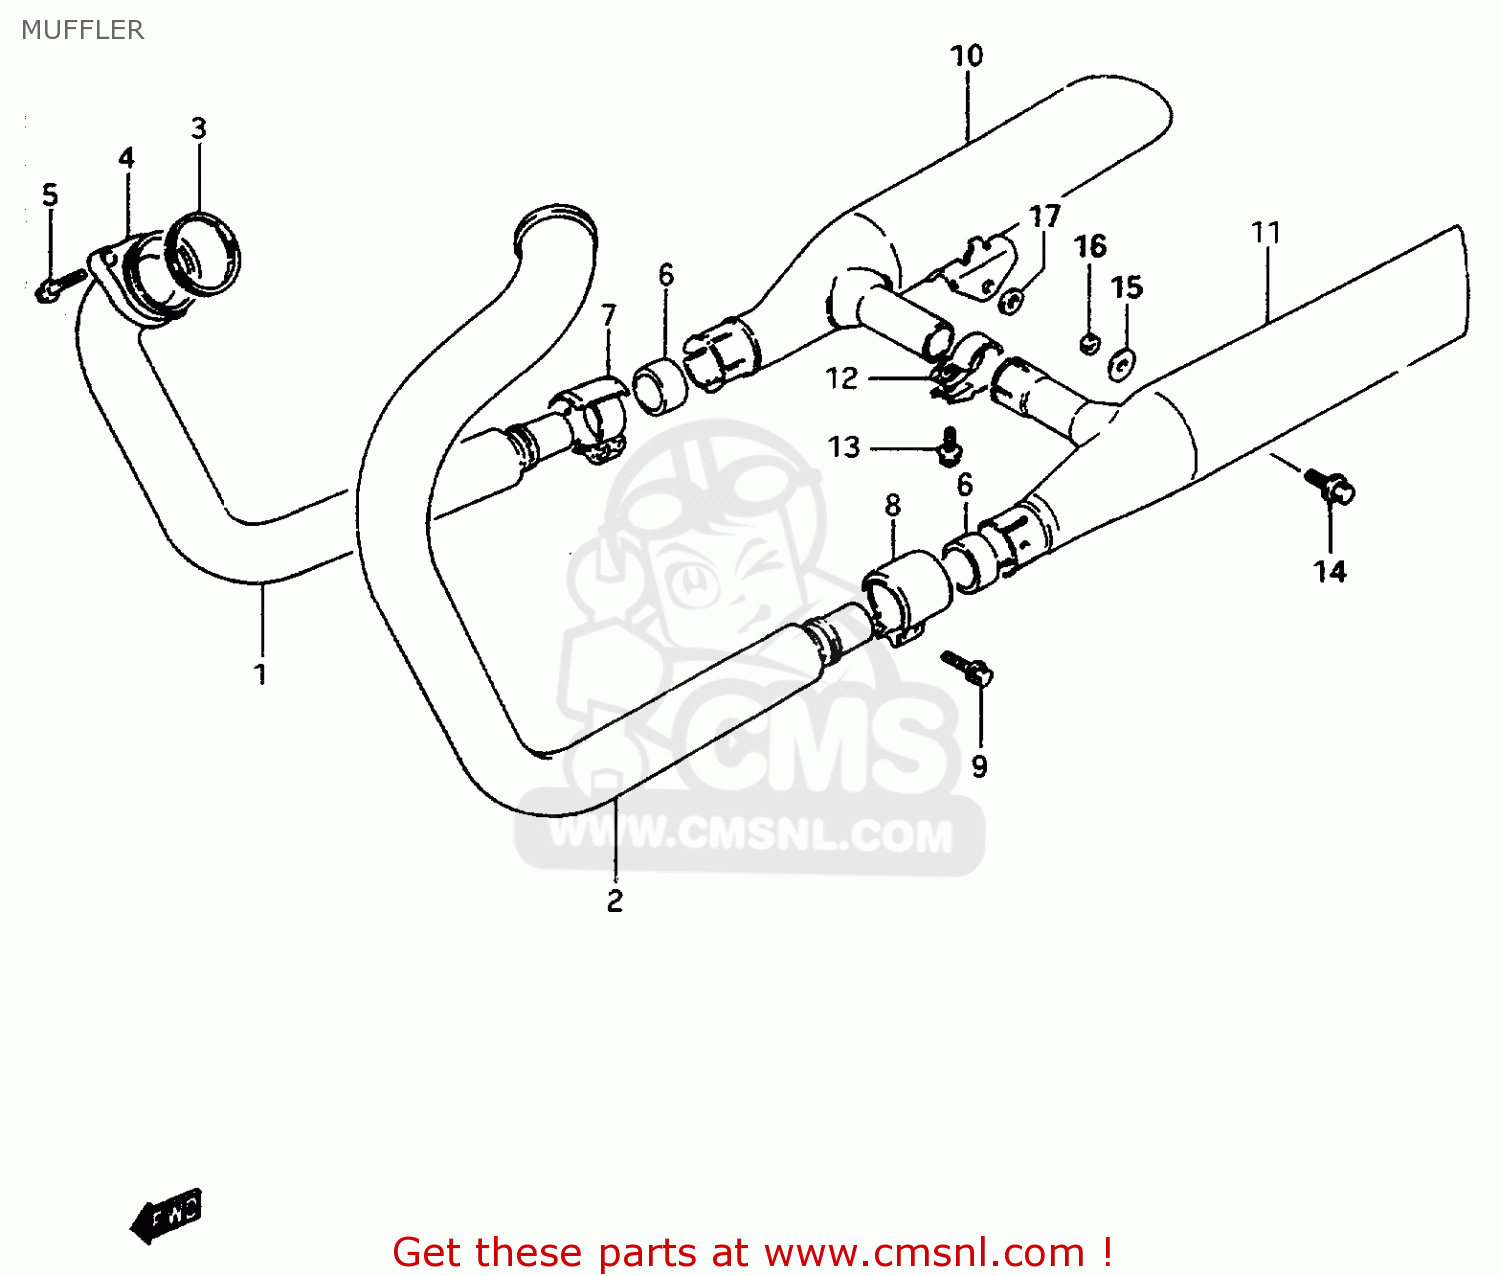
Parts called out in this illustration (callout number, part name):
1	PIPE,EXHAUST,R
2	PIPE,EXHAUST,L
3	GASKET,EXHAUST PIPE (NAS)
4	CLAMP,EXHAUST PIPE
5	BOLT(8X35)
6	CONNECTOR,EXHAUST PIPE
7	CLAMP,MUFFLER CONNECTOR,R
8	CLAMP,MUFFLER CONNECTOR,L
9	BOLT,G/S SWITC
10	BODY,MUFFLER,R
11	BODY,MUFFLER,L
12	CLAMP,EXHAUST COUPLER
13	BOLT
14	BOLT
15	WASHER
16	NUT
17	WASHER (8.5X18X3.2)
